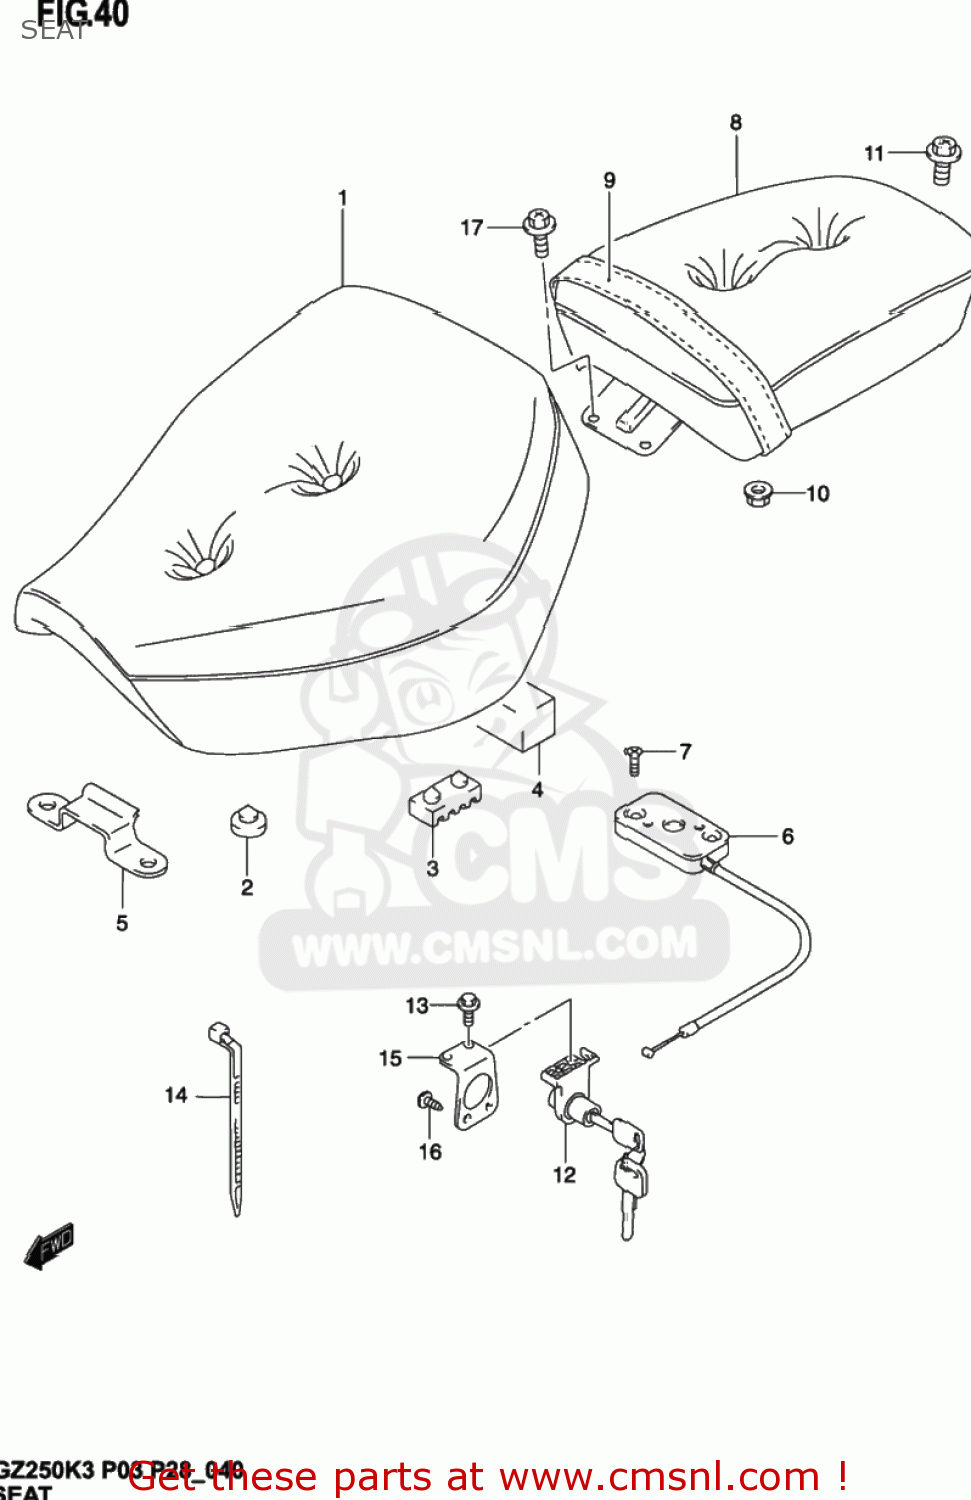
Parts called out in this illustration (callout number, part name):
1	SEAT ASSY
2	CUSHION,FRONT
3	CUSHION,RR
4	CUSHION, TOOL
5	PLATE,FR SEAT HOOK
6	BRACKET,SEAT SUPPORT
7	SCREW
8	SEAT ASSY PILLI
9	BAND, SEAT
10	NUT
11	BOLT(8X16)
12	LOCK SET,SEAT
13	BOLT
14	CLAMP(L:220)
15	BRACKET,SEAT LOCK
16	SCREW
17	BOLT(6X12)
